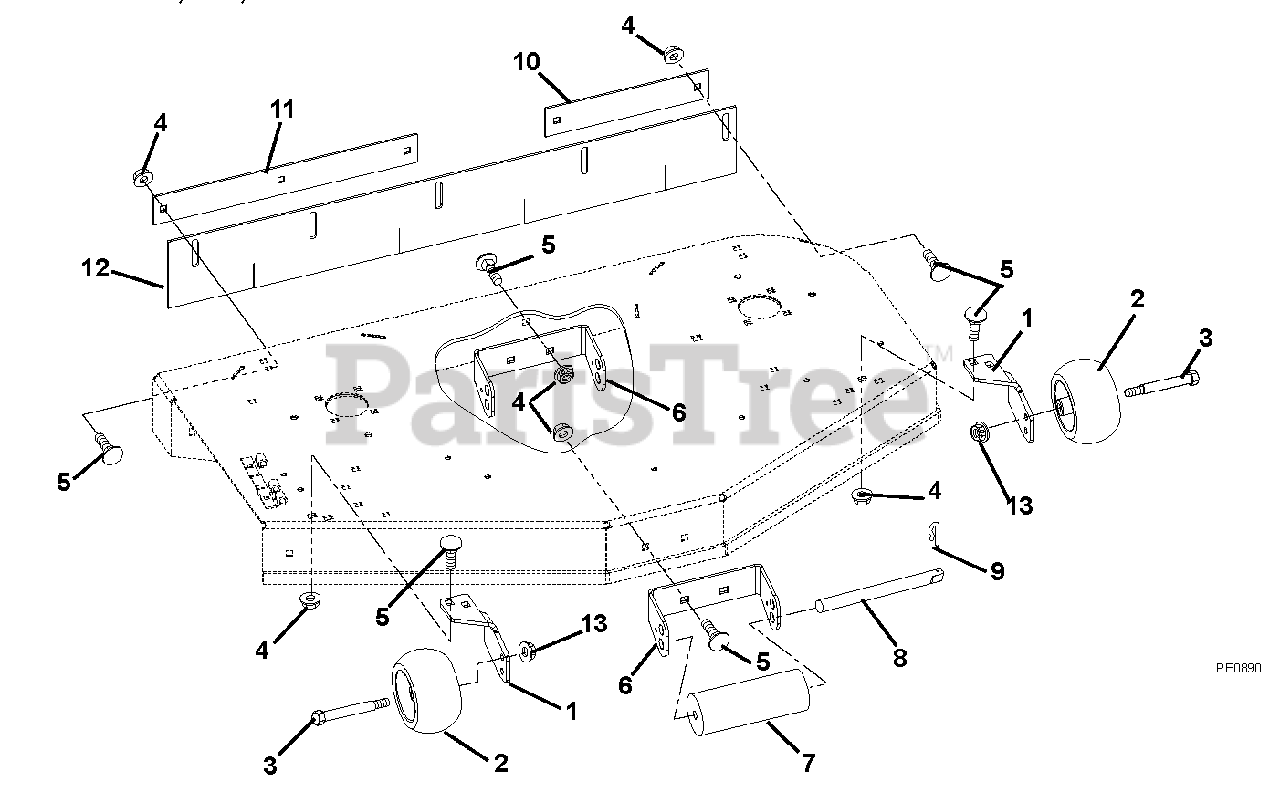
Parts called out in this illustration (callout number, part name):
1	Bracket, Anti-Scalp
2	Wheel 5 x 3
3	Bolt, Shoulder .38-16 x 2.50 Hex Washer Head Grade 5
4	Nut .38-16 Flange Nyloc
5	Bolt-Round Head Square Neck .38-16 x 1.00 Grade 5
6	Bracket, Roller Mount
8	Pin, Roller
9	Pin, Spring Clip
10	Bar, Left Hand Retainer Striper
11	Bar, Retaining Striper (401)
12	Striper, Rubber-44" (401)
13	Nut-Locking-Top-Flange .38-16
